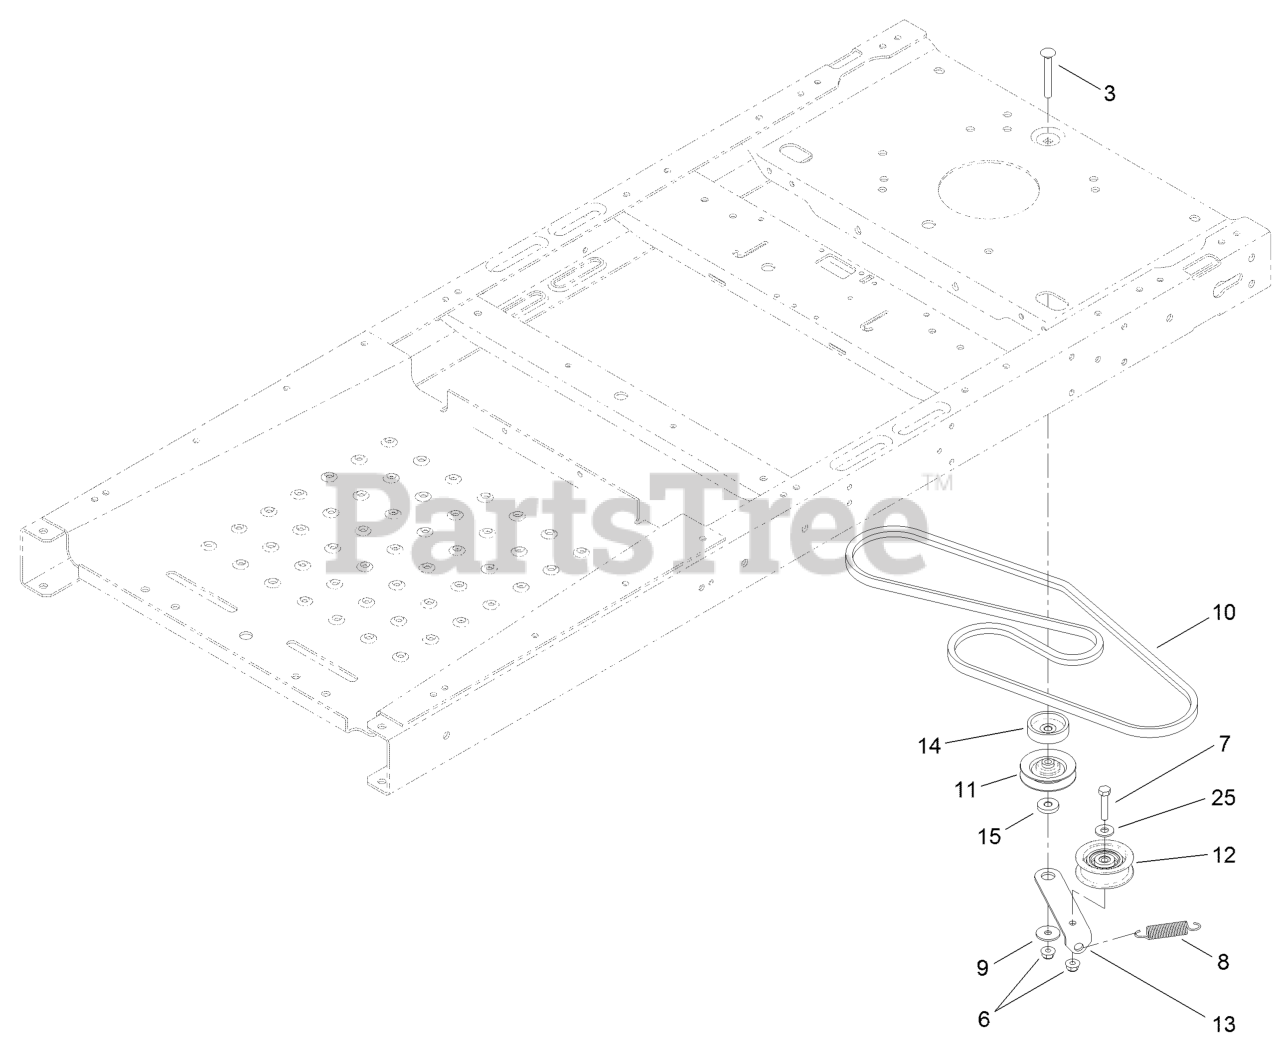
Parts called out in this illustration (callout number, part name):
3	SCREW-CARR
6	NUT-HF, NI
7	SCREW-HH
8	SPRING-RETURN, PEDAL
9	WASHER-PIVOT
10	V-BELT
11	PULLEY-IDLER
12	PULLEY-IDLER
13	ARM-IDLER
15	SPACER-ARM, IDLER
25	WASHER-FLAT
